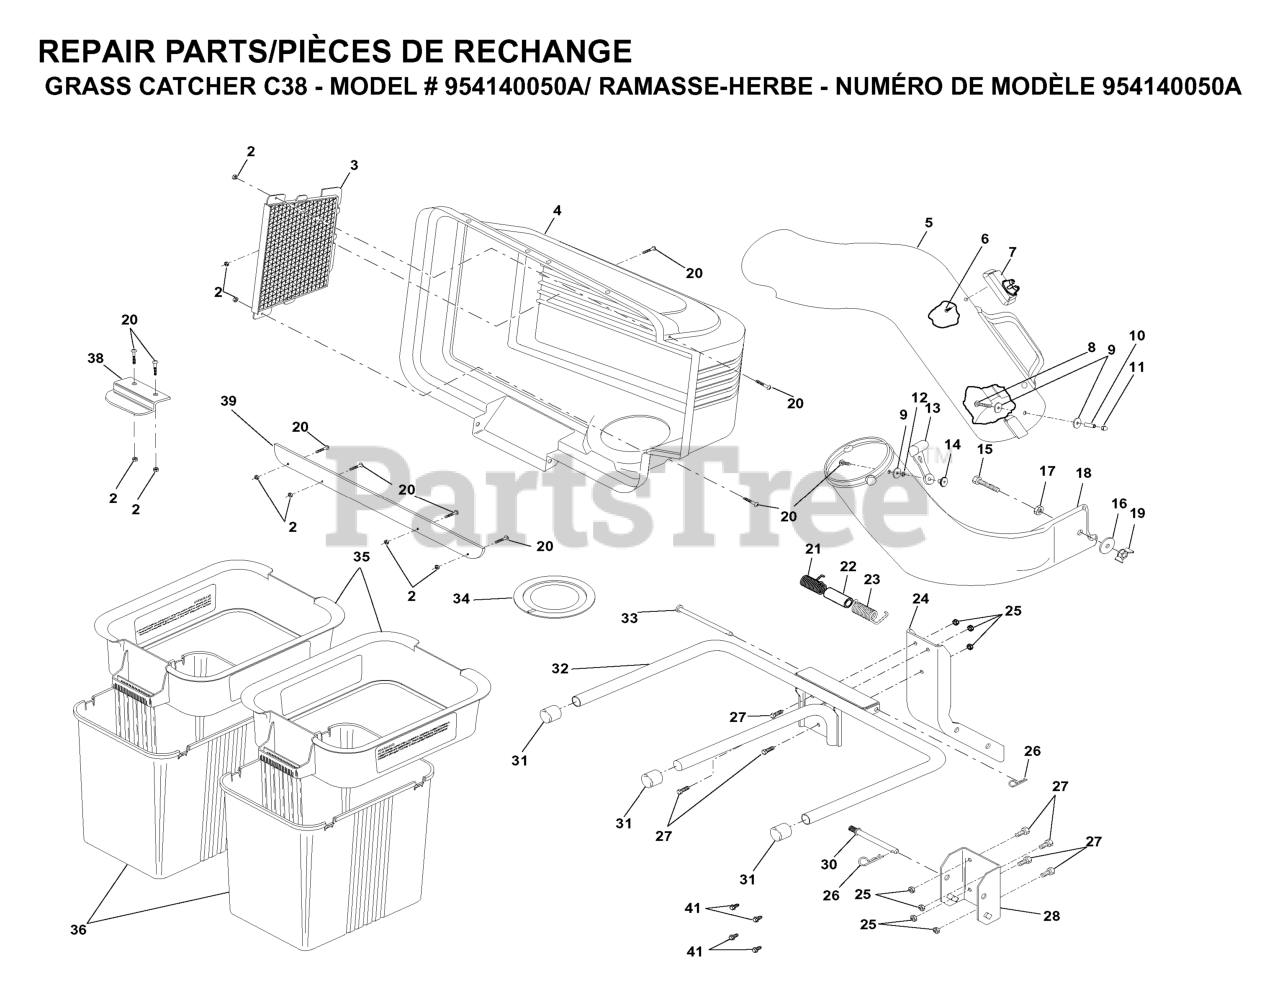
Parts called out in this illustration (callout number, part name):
3	COVER SCREEN
4	COVER
5	CHUTE, UPPER
7	INDICATOR DUMP BAG
8	SCREW
11	NUT
12	LOCKWASHER #10
13	LATCH.HOOD.
14	WELDNUT
15	Bolt, Hex Head 3/8-16 x 1-1/4
16	WASHER
17	LOCKNUT
18	CHUTE.LOWER.38"
20	SCREW
21	SPRING COVER LH
22	SPACER.COVER.BAGGER
23	SPRING COVER RH
24	POST, SUPPORT
25	LOCKNUT
26	RETAINER-SPRNG RB
27	BOLT
28	MTG BRACKET
30	SUPPORT POST PIN
31	TUBING PLUG
32	BAGGER FRAME
33	HINGE PIN
34	GASKET.COVER.BAGGER
35	CONTAINER TOP
36	CONTAINER BOTTOM
38	LATCH CER38
39	STRIP.REINFORCE.BAGGER.2BIN.BL
41	Screw 5/16-18 x 1/2 Hex, Self Tapping 5/16-18 x 1/2
